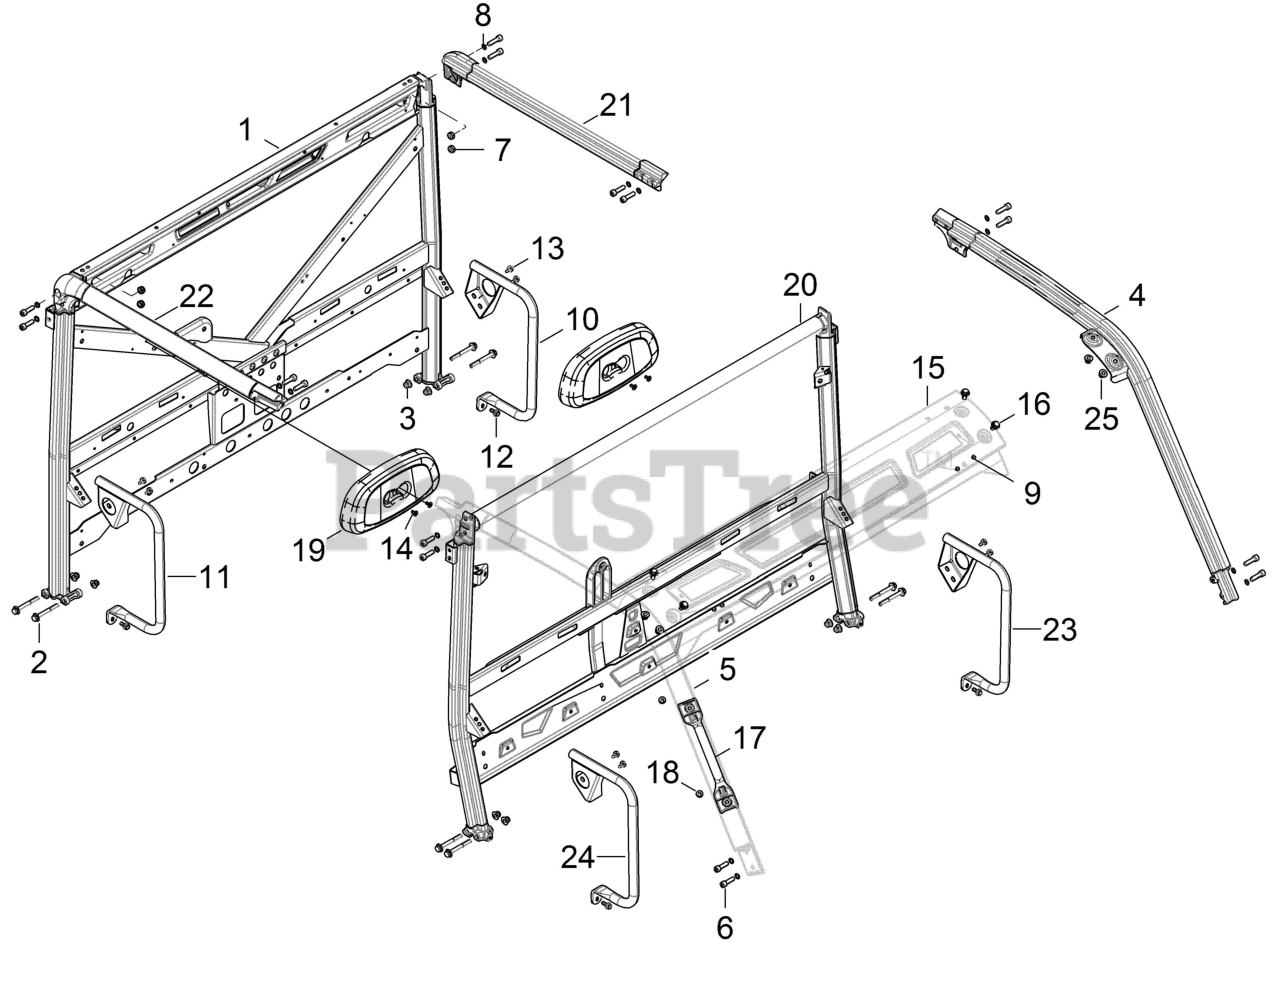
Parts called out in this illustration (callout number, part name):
1	WELD-CAB FRAME,REAR,BLK
2	SCR-HXFL-M10X1.25X80 8.8 ZOD
3	NUT-M10X1.25,FLG,NYLOC-OLIVE D
4	FRONT CAB FRAME, FRONT LH
5	FRONT CAB FRAME, FRONT RH
6	SCR-SH-M10X1.5X35 8.8 ZPB
7	NUT-NYLOC M10X1.5,REF
9	CLIP-PLASTIC,DART
10	HIP BOLSTER, LH
11	HIP BOLSTER, RH
12	SCR-HXFL-M8X1.25X20 8.8 ZOD P3
13	SCR-TXTH-M6X1.0X25 RIE
14	RIVET(50)
15	WELD-PLATE-WNDSHLD,UPR,CAB,BLK
16	BOLT-M10X1.5X20,HXFLG,W/PATCH
17	HANDLE-GRAB,ROPS,BLK
18	BOLT-M8X1.25X20,HXFLG,TAP/R-OD
19	HEADREST-GRAVELY,GRAY
20	WELD-CAB FRAME,CENTER 6 PASS
21	WELD-CAB FRAME,REAR,LH,M.BLK
22	WELD-CAB FRAME,REAR,RH,M.BLK
23	HIP BOLSTER FRONT: 219
24	HIP BOLSTER FRONT: 219
25	NUT-M10X1.25,FLG,NYLOC-OLIVE D
